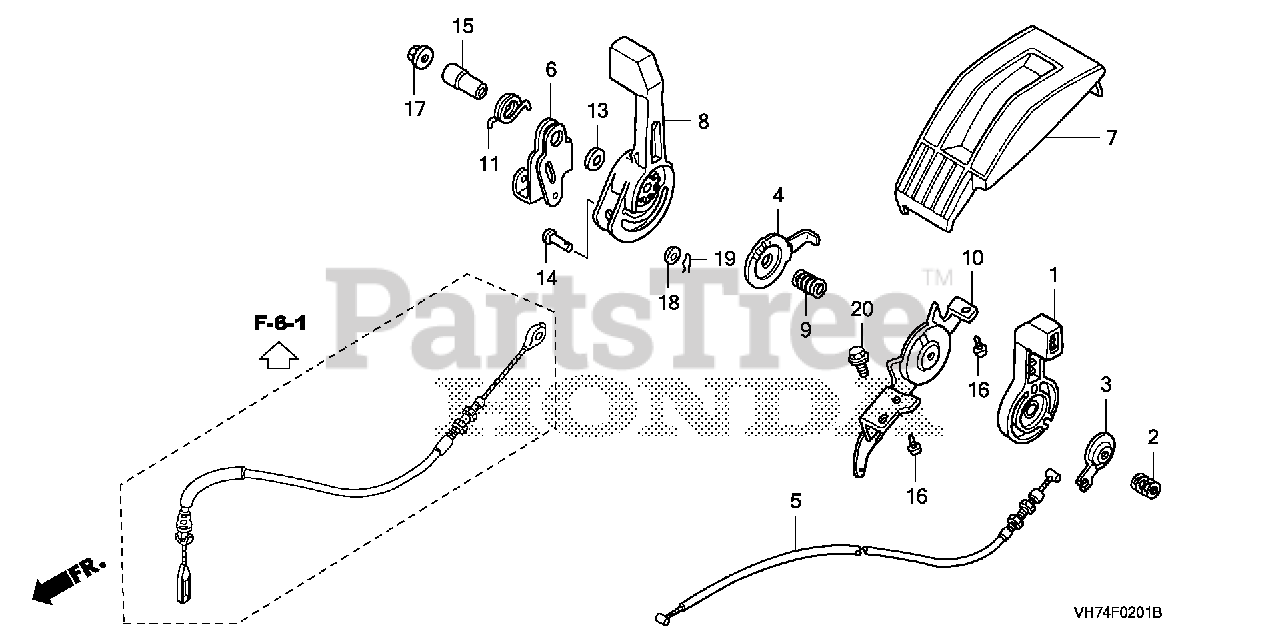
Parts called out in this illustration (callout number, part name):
1	LEVER, THROTTLE
2	SPRING, THROTTLE LEVER
3	SEAT, SPRING
4	SEAT, SPRING
5	CABLE, THROTTLE
6	ARM, CHANGE LEVER
7	COVER, CONTROL
8	LEVER, CHANGE
9	SPRING, CHANGE LEVER
10	STOPPER, LEVER
11	SPRING, ARM RETURN
13	WASHER (10.5X30)
14	PIN (6X22)
15	COLLAR, CHANGE LEVER
16	SCREW, TAPPING (5X12)
17	NUT, FLANGE (6MM)
18	WASHER, PLAIN (6MM)
19	PIN, LOCK (6MM)
20	BOLT, FLANGE (6X10)
